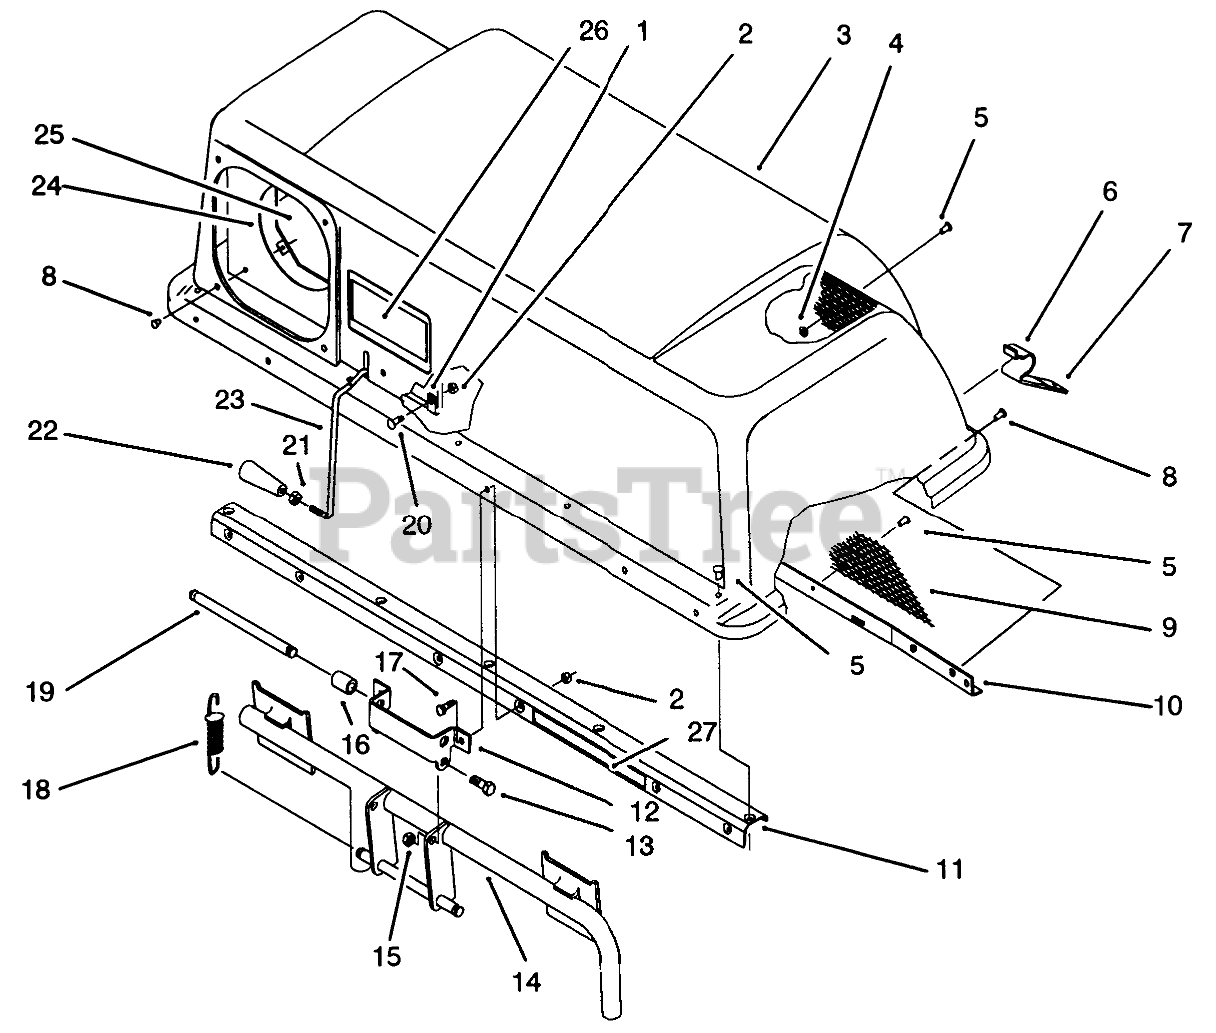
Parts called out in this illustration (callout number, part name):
1	Clip
2	NUT-LOCK, NI
3	TOP-BAGGER
4	Washer
5	RIVET-BLIND
6	Latch-Bag
8	Pop Rivet
9	SCREEN-BAGGER
10	SUPPORT-SCREEN B
11	Stiffener Assembly (Incl Ref. #27)
12	HINGE-BAG TOPB
13	SCREW-HH
14	FRAME ASM
15	NUT-LOCK, NI
16	SPACER
17	SCREW-HH
18	SPRING-EXTENSION
19	PIN-SPRING
20	Screw
21	NUT-JAM
22	HANDLE-TAPERED
23	FEELER-FILL, BAG
24	SEAL-CHUTE
25	CLAMP-SEAL
26	DECAL
27	Decal
